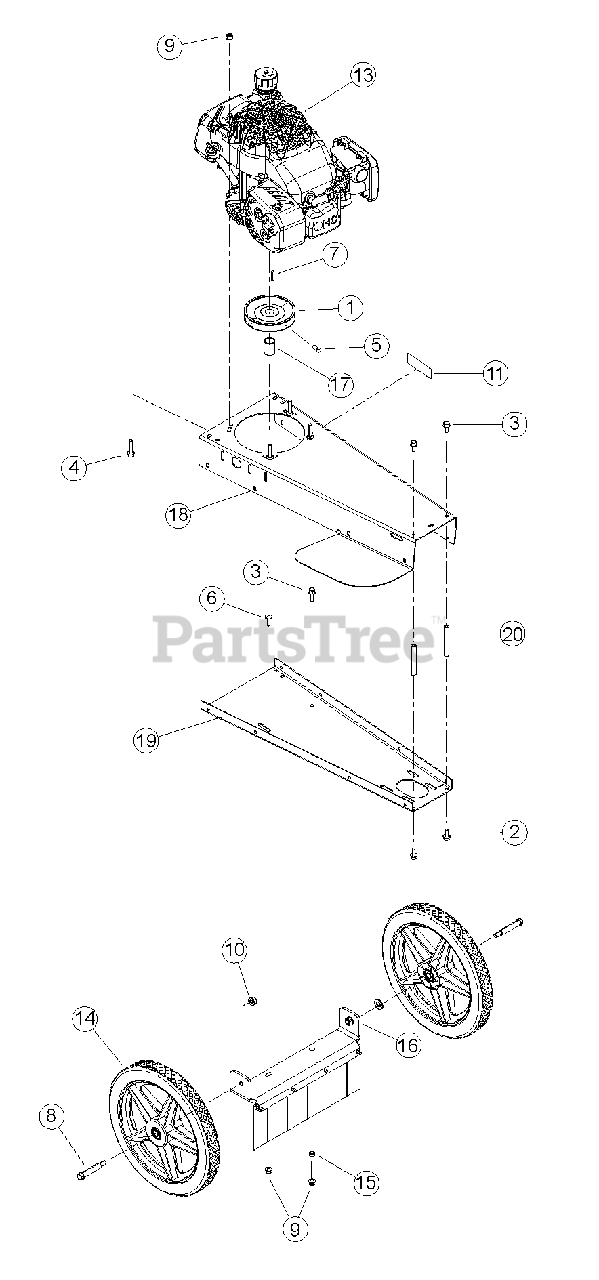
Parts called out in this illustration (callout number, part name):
1	PULLEY, 5.0 X 7/8 AB
2	BOLT, 5/16 X 3/4 FLANGE NC
3	BOLT, 5/16 X 1 FLANGE NC
4	BOLT, 5/16 X 1-1/2 FLANGE NC
5	SCREW, 5/16-18 X 5/8 SQ HD SET
6	BOLT, 5/16 X 1" GR5 CRG ZP
7	SQUARE KEY, 3/16" X 1.00"LG
8	BOLT, 3/8-16 X 3-1/4 FLANGED SHOULDER
9	NUT, 5/16-18 NYLOCK-FLANGE
10	NUT, 3/8-16 NYLOCK FLANGE
11	DECAL, SERIAL NUMBER
13	ENGINE, EA190V SUBARU BRAKE
14	WHEEL, 14 X 1.75 TRIMMER
15	SPACER, .334 X .50 X .29
16	PLATE, TRIMMER AXLE
17	SPACER, 1 1/16 OD X 14 GA X 1.40
18	BODY, TRIMMER STANDOFF
19	BOTTOM, TRIMMER STANDOFF
20	STANDOFF, WHEELED TRIMMER BODY
